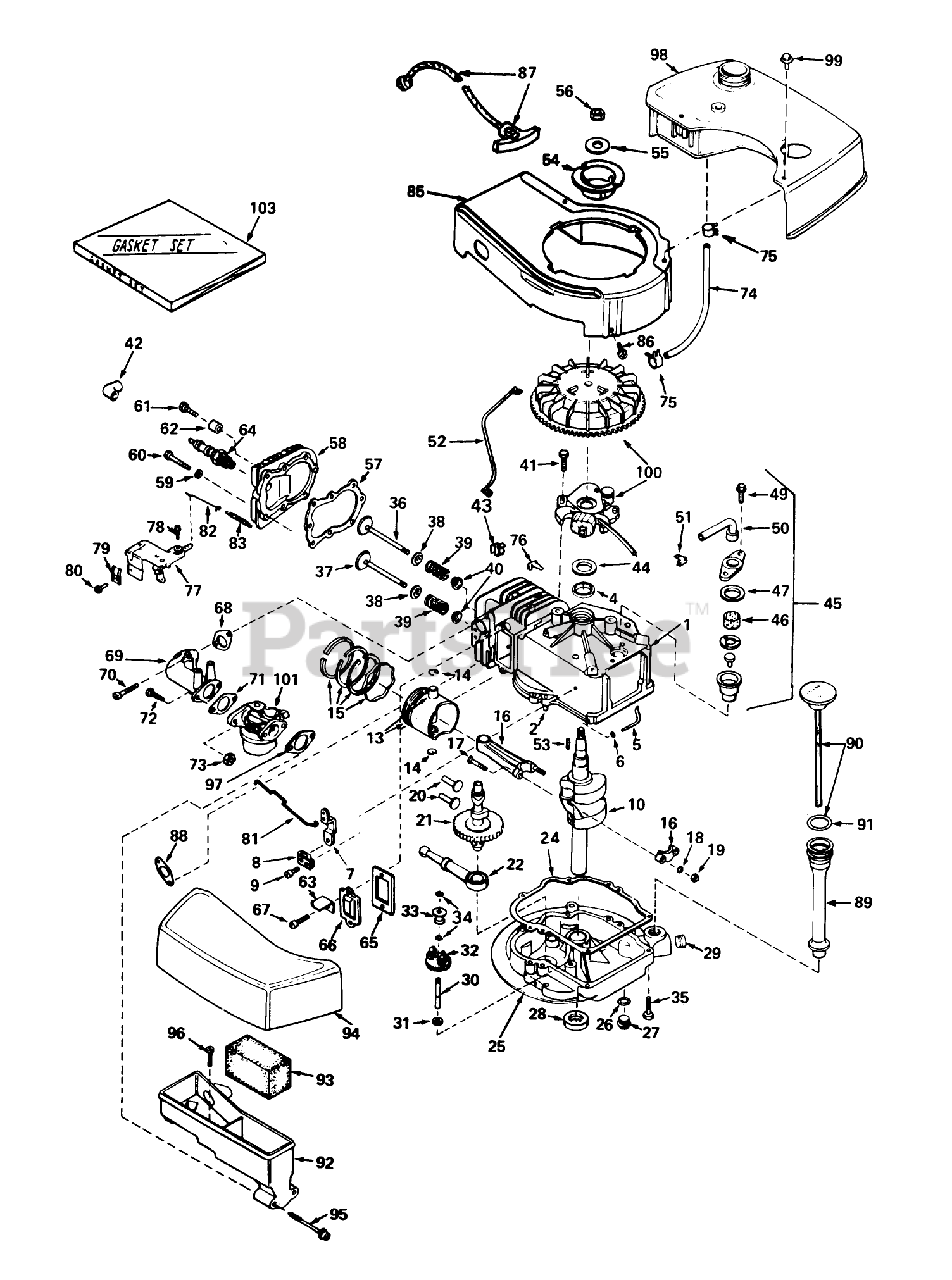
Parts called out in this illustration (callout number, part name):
1	Cylinder Assy. (Incl. Ref. #2, 4 105)
2	Pin-Dowel
4	OIL SEAL
5	Rod, Governor (Incl. No. 36)
6	Washer-Flat
7	Governor Lever
8	Clamp-Lever, Governor
9	Screw
10	Crankshaft
13	Piston Pin Assembly (Incl. 2 of No. 14) (.010 Oversize)
13	Piston Pin Assembly (Incl. 2 of No. 14) (.020 Oversize)
14	Ring-Retaining, Piston Pin
15	Ring Set Piston (Std.)
15	Ring Set Piston (.010 Oversize)
15	Ring Set Piston (.020 Oversize)
16	Rod Assy., Connecting (Incl. Ref. #17)
17	Bolt, Connecting
18	Washer
19	LOCKNUT
20	Lifter-Valve
21	Camshaft(Mech.Comp. Release)
22	Oil Pump ASM
24	Gasket, Mounting
25	Filter, Air Cleaner
26	Gasket-Oil Drain
27	Plug Oil Drain
28	Seal Oil
29	Plug Oil Drain
30	Shaft-Governor
31	Washer-Flat
32	Governor Gear ASM
33	Spool-Governor
34	Ring-Retaining
35	Screw (1/4-20 x 1-1/4)
36	Valve, Intake (Incl. Ref. #38, 39 40) (Std.)
36	Valve, Exhaust (1/32" Oversize) (Incl. Nos. 8, 9 10)
37	Valve, Exhaust (Standard) (Incl. Nos. 8, 9 10)
37	Valve, Exhaust (1/32" Oversize) (Incl. Nos. 8, 9 10)
38	Cap-Upper Valve Spring
39	Spring-Valve
40	Cap-Valve, Spring
41	Screw
42	Cover-Spark Plug
43	51004 GIL ROTARY TI
44	Gasket Stator
45	Breather Assy. (Incl. Ref. #46, 47, 49, 50 51 )
46	Element-Breather
47	Gasket-Breather
49	Screw, Hex Hd. w/Conical
50	Tube, Breaker
51	Clip, Breather
52	Wire, Ground
53	Key-Flywheel
54	Pulley Starter
55	Washer-Spring
56	Hex Nut
57	63573 GIL 42 SNWTHW
58	Head Cylinder
59	Washer
60	Screw
61	Screw Hex Hd. Cap
62	Space
63	Retainer Clip
64	Plug, Spark (Champion RCJ-8)
65	Gasket-Breather
66	Cover-Valve
67	Screw
68	Gasket, Intake
69	Pipe, Intake
70	Screw (1/4-20 x 1)
71	Gasket-Carburetor
73	Nut and Lock Washer (1/4-28)
74	Line-Fuel
75	Clamp-Line, Fuel
76	Clip-Wire
77	Control Assy., Speed (Incl. Nos, 76, 78 89)
78	Screw (10-24 x 3/4)
79	Conduit
80	Screw (10-32 x 3/8)
81	Link Governor
82	Link Governor Spring
83	Spring Governor
85	53024/VAR.GT O/P W/
86	Screw
87	Rope Assy., Starter
88	Gasket Exhaust
89	Tube Fill
90	Dipstick, Oil (Incl. Ref. #101)(Twist Lock)
91	O-Ring
92	Body Air Cleaner
93	Filer, Air
94	Cove, Air Cleaner
95	Screw Fil Hd.
96	Screw, Hex Hd.
97	Gasket-Air Cleaner
98	Tank Fuel
99	Screw (10-32 x 35/64)
100	Magneto
101	Carburetor (Incl. No. 71)
103	53024/VAR.16HP O/P
